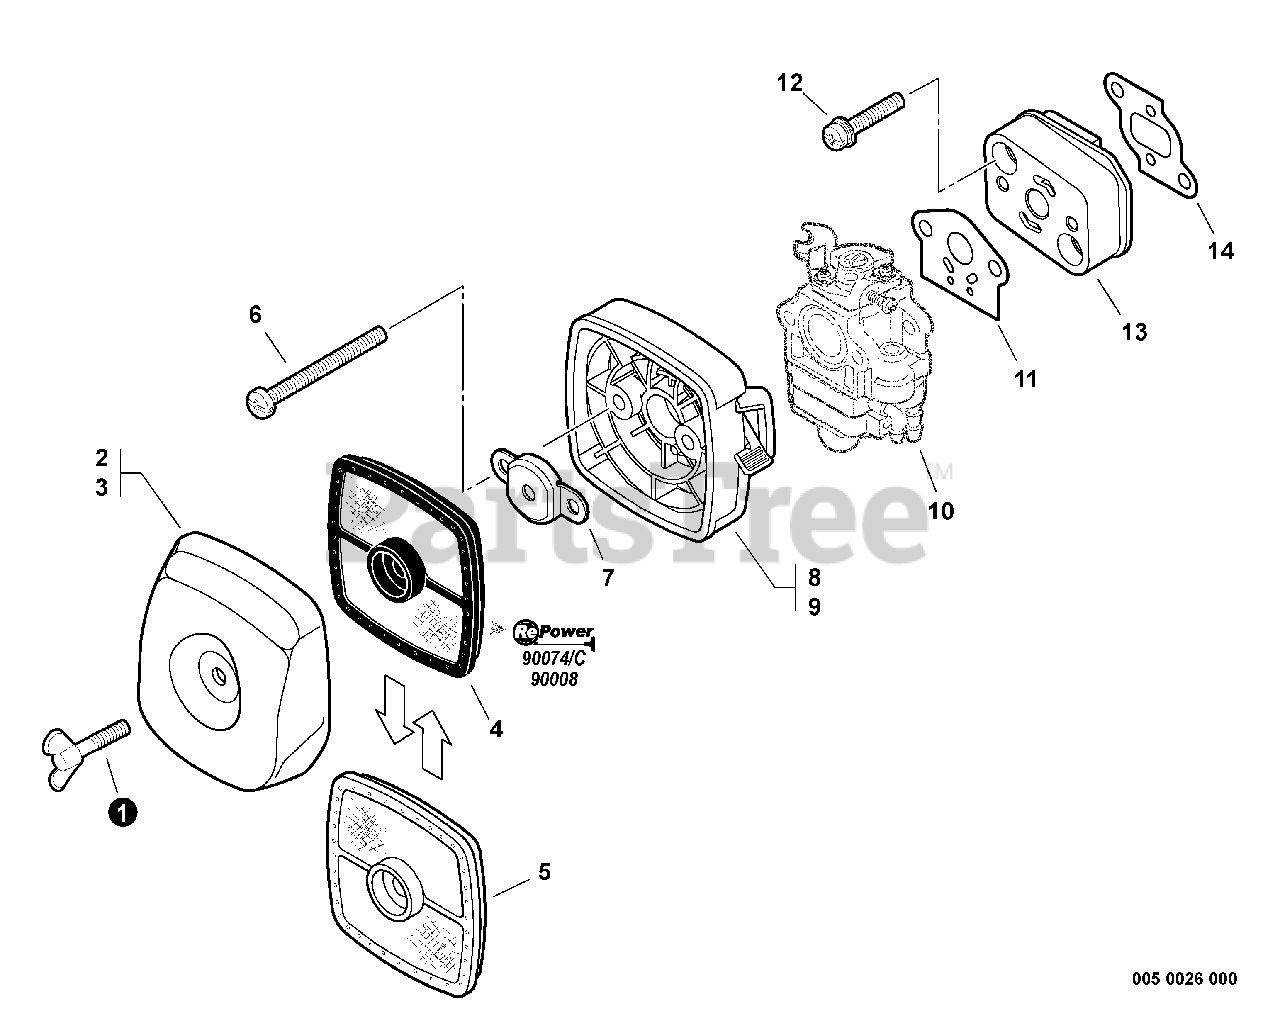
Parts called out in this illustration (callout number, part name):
1	THUMBSCREW
2	COVER, AIR FILTER - GRAY
3	COVER, AIR FILTER - BLACK
4	FILTER, AIR - DOUBLE LAYER
5	FILTER, AIR - SINGLE LAYER
6	SCREW - 5X60
7	PLATE, PREVENT
8	CASE, AIR FILTER - GRAY
9	CASE, AIR FILTER - BLACK
10	CARBURETOR
11	GASKET, INTAKE
12	SCREW - 5X25
13	INSULATOR, INTAKE
14	GASKET, INTAKE
15	RePower TUNE-UP KIT
16	RePower FILTER KIT
